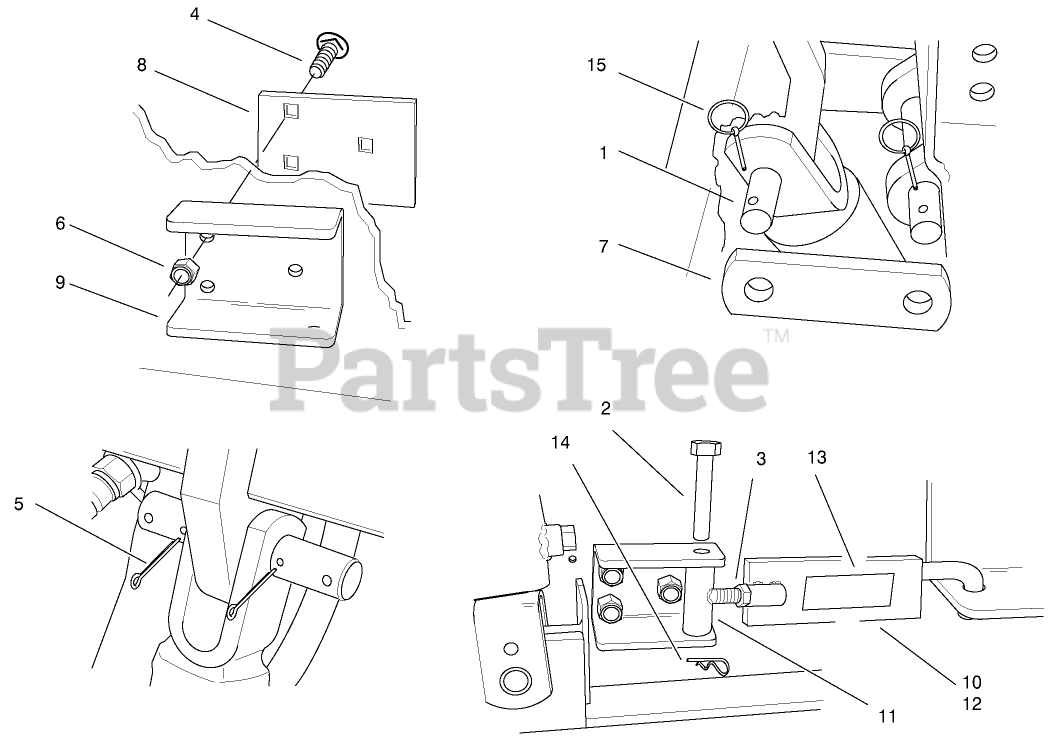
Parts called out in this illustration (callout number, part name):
1	Pin-Cylinder Lock
2	PIN-CLEVIS
3	NUT-JAM
4	SCREW-CARR, SHORT NECK
5	PIN-COTTER
6	NUT-LOCK, NI
7	Strap-Lock
8	Plate-Anchor
9	Bracket-Anchor
10	LH Clevis ASM
11	Tube ASM
12	RH Clevis ASM
13	DECAL-TIEDOWN
14	PIN-HAIR
15	PIN-LYNCH
